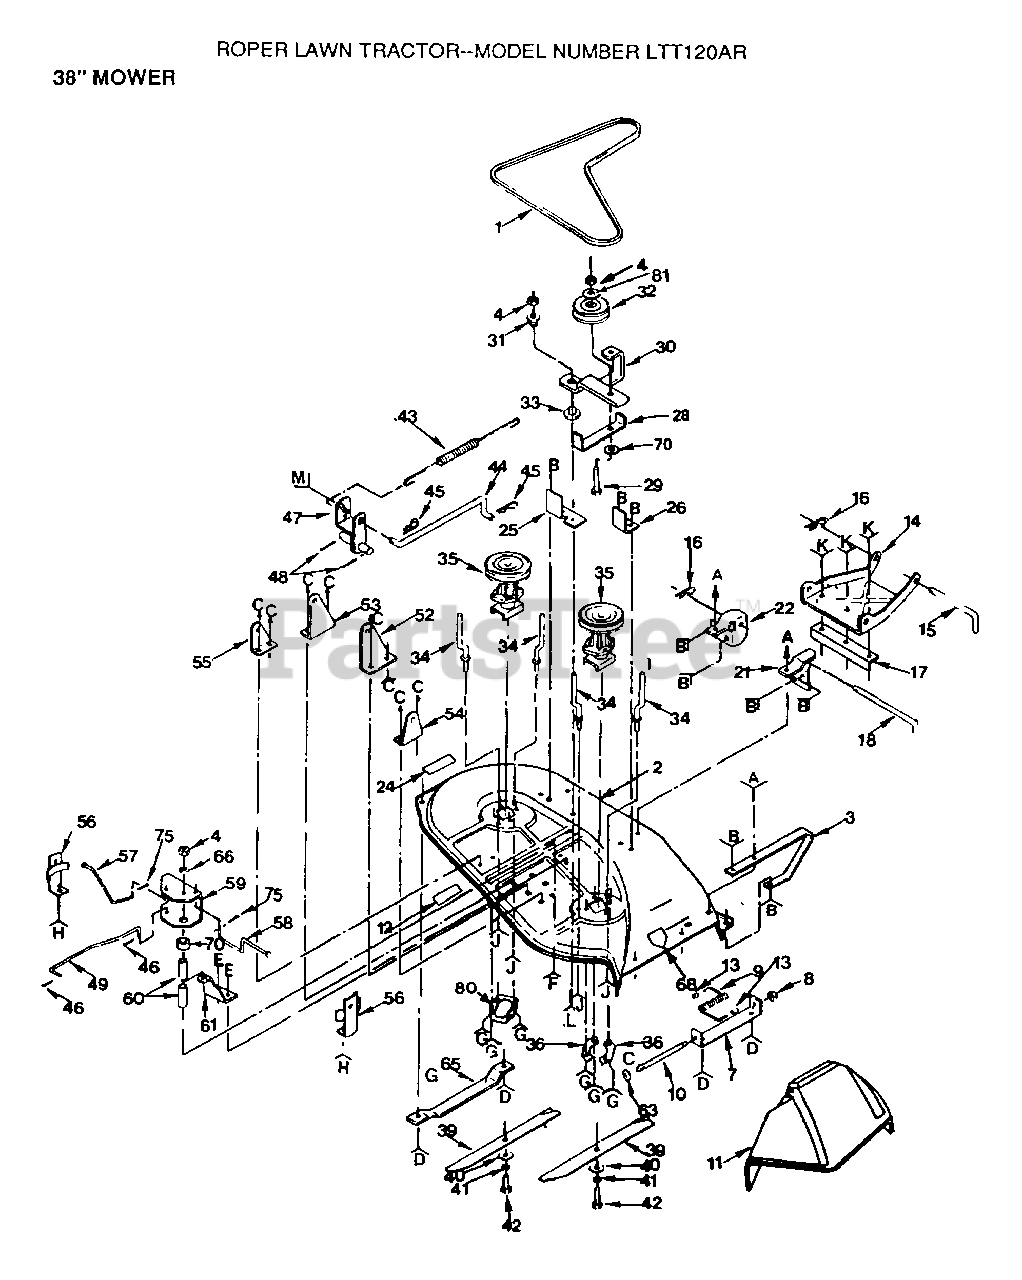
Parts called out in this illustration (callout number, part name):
1	BELT-V.79.1.MWR
8	NUT PUSH M
10	ROD-HINGE T
11	DEFLECTOR-SHLD T
12	DECAL.LT
13	CAP-SLEEVE LT
14	LINK.PARALLEL
15	"ROD, FRT. PARAL T"
16	SPRING.RETAINER
17	LINK STOP
18	HINGE PIN T
21	BRACKET RH LT
22	BRACKET LH T
24	DECAL YT
25	SUPPORT ARM T
26	STOP T
31	SPACER RETAINER
32	PULLEY IDLER
33	"WASHER, WEAR LT"
34	BELT KEEPER LT
35	"JACKSHAFT.38""LT"
36	SUPPORT PLATE LT
39	"BLADE.38"" HI-LI"
40	WASHER
42	BOLT.3/8-24X1-1/2
45	SPRING.RETAINER
47	ROCKSHAFT T
49	ROD BRAKE LT
54	"BRKT,SUSP RH T"
55	"BRKT,SUSP REAR LH"
56	BRAKE LT
57	"ROD, BRAKE LH LT"
58	ROD BRAKE LT
59	"BRK,BRAKE,PVT LT"
60	SPACER BRAKE LTV
61	BRACKET SUPT LTV
63	WASHER
65	RUNNER-LH M
66	WASHER
68	DECAL WARNING
80	SUPPORT T
81	WASHER
